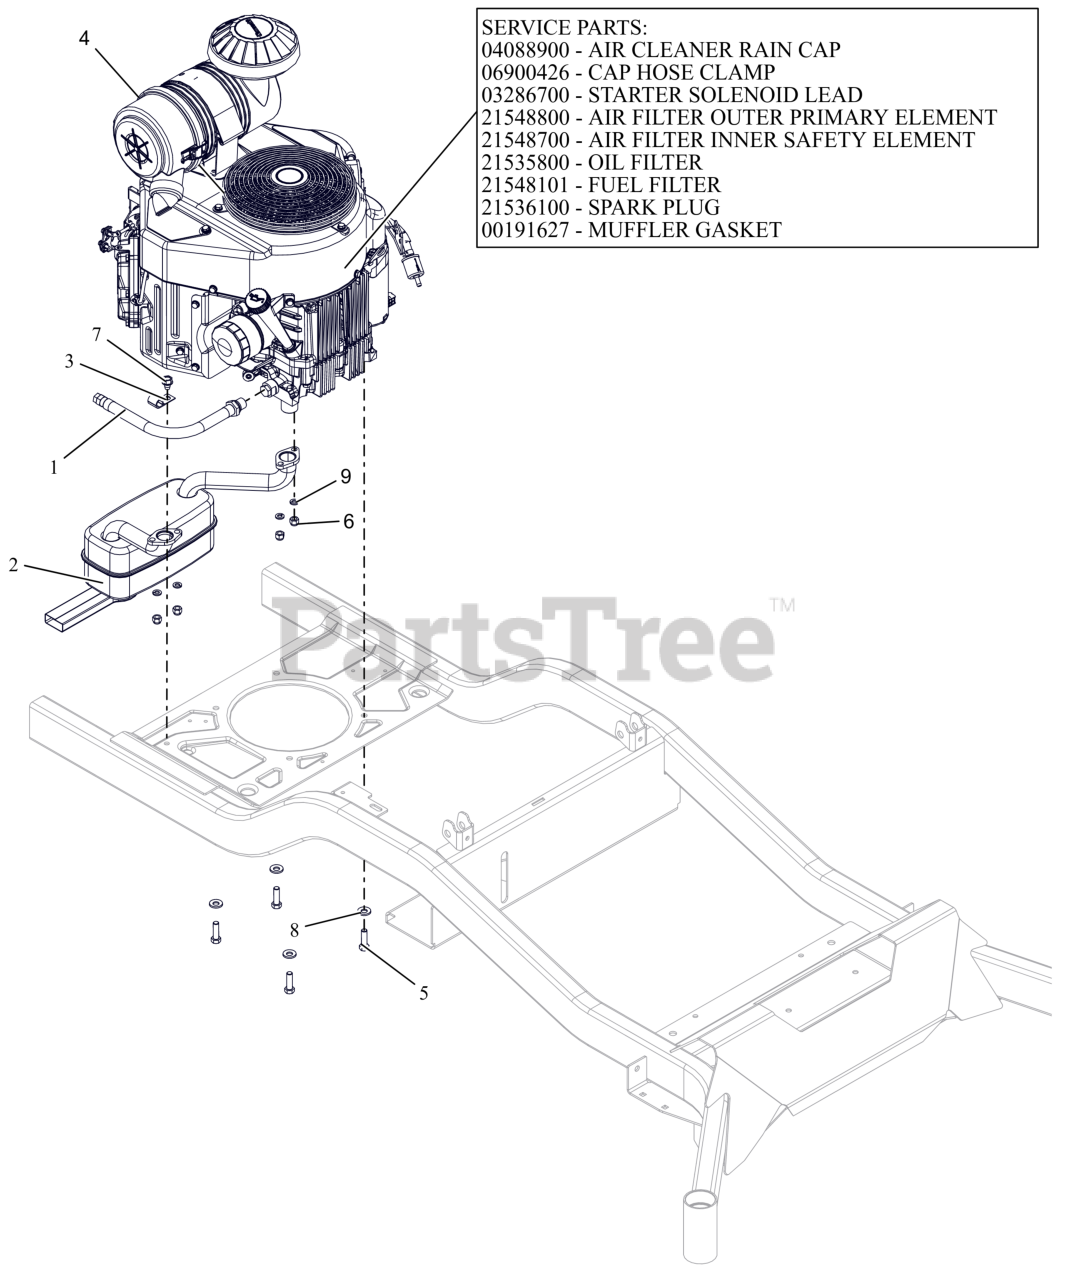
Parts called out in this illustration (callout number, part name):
1	HOSE, OIL DRAIN
2	MUFFLER, KAWASAKI
3	J-CLAMP
4	ENGINE, KAWASAKI - FX730
5	BLT, HEX .38-16X1.25 G5 ZCC NT
5	FILTER, OUTER
5	FILTER, INNER - KAW
5	FILTER,OIL - KAW
5	FUEL FILTER-KAWASAKI FR
5	PLUG, SPARK
5	GASKET, MUFFLER S/O
5	CAP, KAW 11065-7025
5	CLAMP, HOSE #36 SS 1.813-2.75
5	LEAD - STARTER SOLENOID
6	NUT, LK-CTR-JAM M8-1.25 GR8.8 ZC120
7	SCR,TAP .375-16X.50 HWH TR ZCC
8	WASHER, 3/8" SPRING DISC
9	WSHR,LK-REG .312X.078 ZCC
